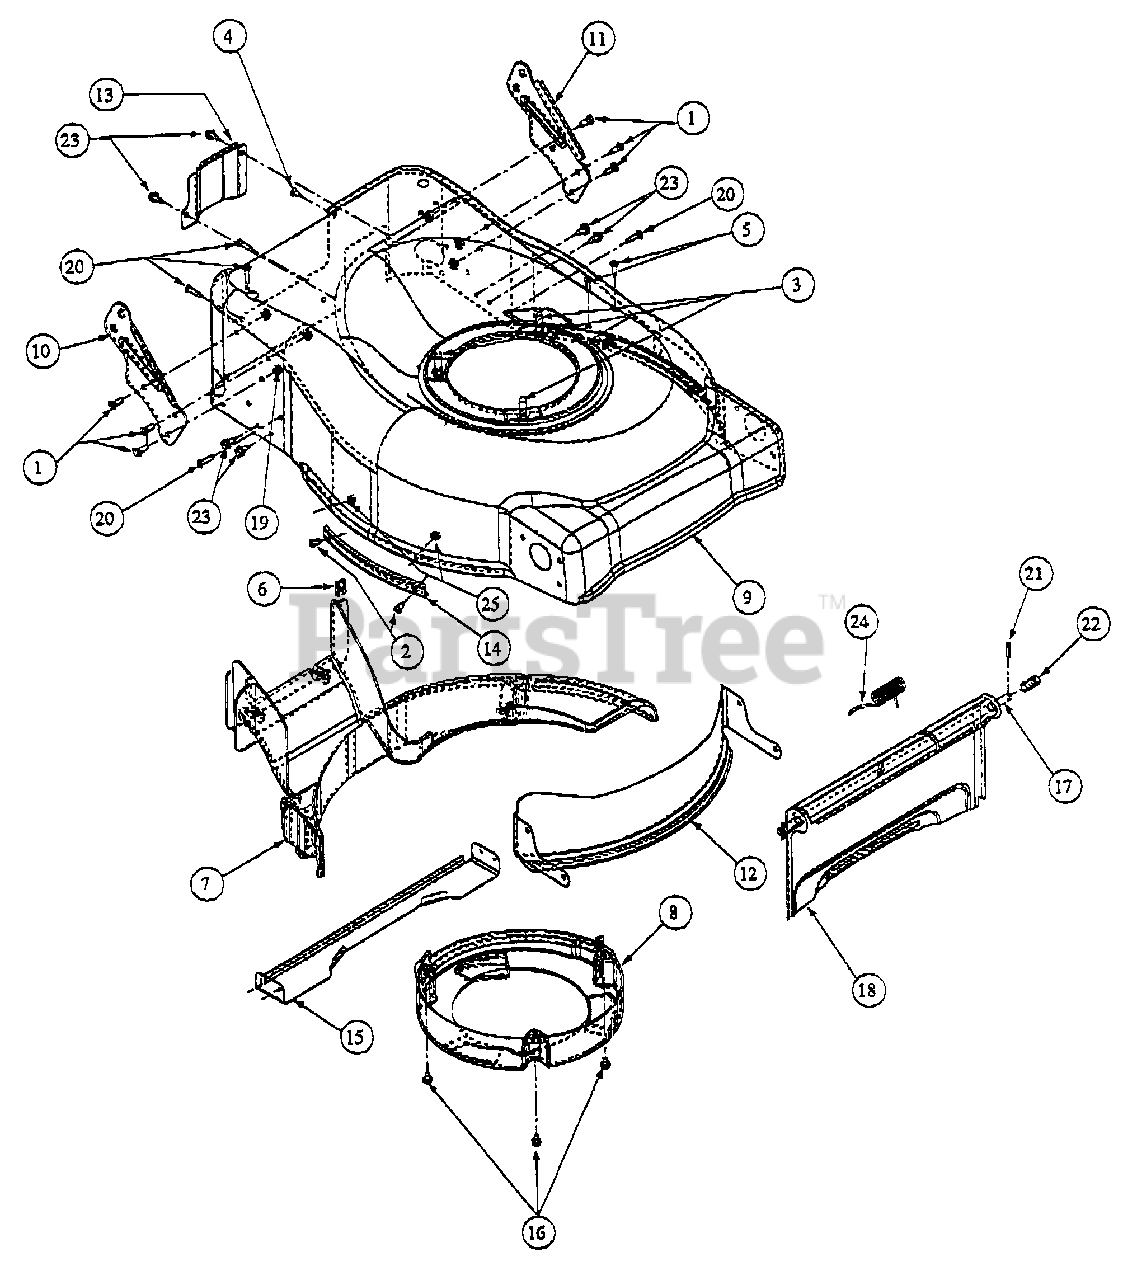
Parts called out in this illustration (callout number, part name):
1	HHCS, 1/4-20, .620, GR5, Standard
2	Screw Button HD, 1/4-20 x .5
3	Screw, TTSems, 3/8-16, 1.250, HXLWS
4	Screw, B, 10-16, 0.500, TRUSTRX1
5	Screw, HL, 12-16:0.750, TRUSTRX1
6	U-Nut, 10-16
7	Baffle, RR, 21" Commercial
8	Cover, 21" Commercial
9	Deck, 21 Commercial
10	Bracket, Handle, RH Commercial
11	Bracket, Handle, LH Commercial
12	Baffle Front Commercial 10.81 R
13	Cover Plate
14	Guard, Deck Side Flange
15	Bracket, Support Baffle
16	Screw, TT, 1/4-20, 0.375, Hex indicator Washer
17	Rod, Pivot, Chute Door, .375 D1
18	Door, Grassbag, 21" RB
19	Nut, 1/4-20, Hex Flange, Lock Group F
20	Screw, HL, 12-16. 1.000, TRUSTRX1
21	Cotter Pin, INT .072 x 1.12 LG
22	Spacer, .375 x .50 x 1.02 LG
23	Screw, AB, 1/4-14, 0.625, Hex Indicator Washer
24	Spacer, Torsion, LH 0.120 x 15C
25	Hex Nut, 1/4-20 GRC, Lock
